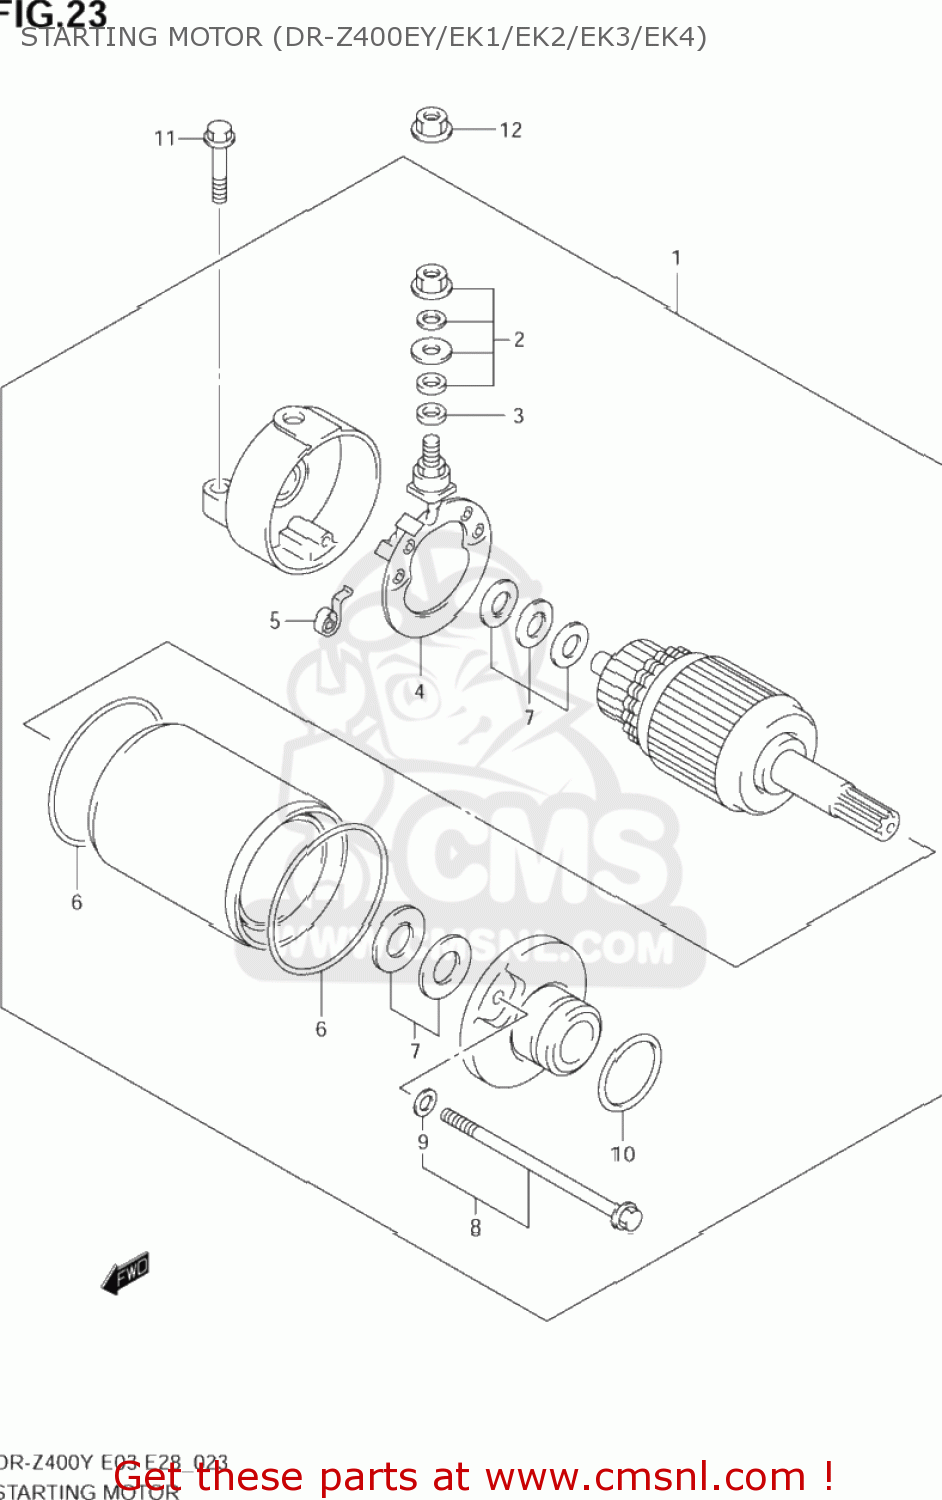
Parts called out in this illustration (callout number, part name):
1	MOTOR ASSY,STARTING
2	BRUSH TERMINAL SET
3	O RING
4	BRUSH HOLDER SET
5	SPRING,BRUSH
6	O RING
7	SHIM SET,STARTING MOTOR
8	BOLT SET
9	O RING
10	O RING(D:3,ID:24.5)
11	SCREW
12	NUT
